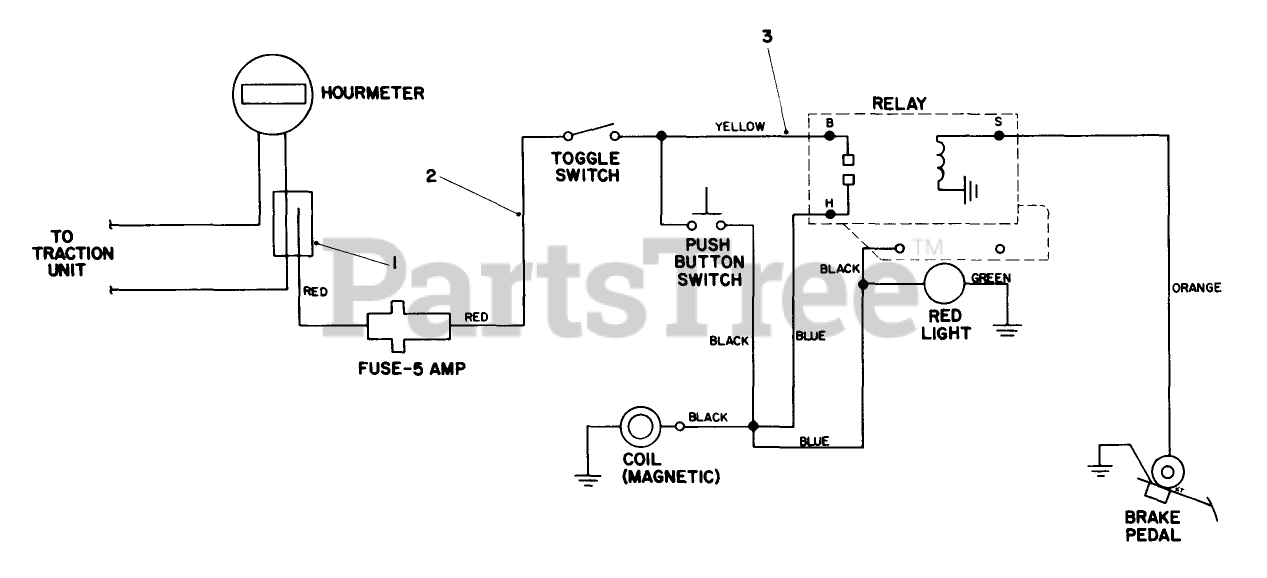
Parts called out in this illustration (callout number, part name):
1	TAP CONNECTOR
2	HARNESS
3	WIRE ASM
